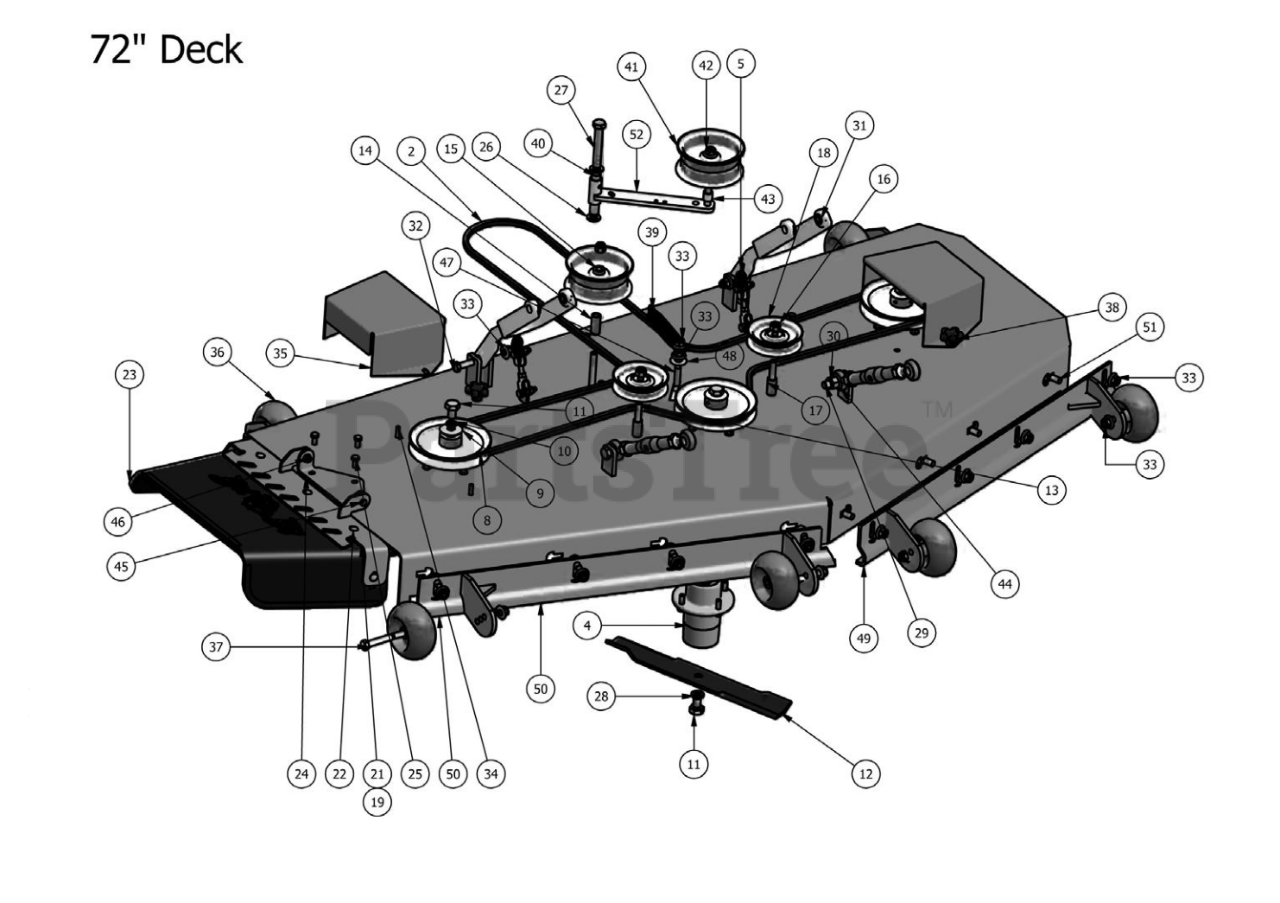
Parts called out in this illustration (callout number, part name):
1	72" Deck Shell
2	72" Deck Belt (Diesel)
3	4 Link Chain Assembly
4	Double Bearing Spindle
5	3/8" x 1 1/4" Hex Bolt
6	3/8" Lock Washer
7	3/8-16 Hex Nuts Zinc
8	7" Deck Pulley
9	Cup Washer
10	1/2" Lock Washer
11	5/8" x 1 1/2" Hex Bolt Grade 8
12	72" Fusion High Lift Blade
13	1/2" x 3 1/2" Grade 8 Bolt
14	1 3/4" Pulley Spacer
15	5 3/4" Deck Idler Pulley
16	1/2" Nylock Nut
17	1 1/2" Diesel Pulley Spacer
18	4 3/4" Idler Pulley
19	72" Lower Hanger
20	5/16" Nylock Flange Nut
21	72" Discharge Chute Upper Hanger Plate
22	5/16" x 1 1/4" Carriage Bolt
23	Rubber Discharge Chute
24	Discharge Chute Hanger (deck mounted)
25	3/8" x 3/4" Hex Bolt
26	.635 ID Plastic Washer
27	5/8" x 4" Hex Bolt
28	5/8" Lock Washer
29	5/8" x 2 1/2" Hex Bolt
30	5/8 Std NC Nylock Nut
31	Deck Arm Assembly
32	1/2" x 2 1/2" Hex Bolt
33	1/2 Nylon Flange Nut-Orange
34	5/16" x 1 1/4" Hex Bolt
35	72" Pulley Cover
36	Anti-Scalp Rollers
37	1/2" x 4" Bolt (Grade 8)
39	Deck Idler Spring 2009
40	5/8 x 1 1/8 Brass Bushing
41	5 3/4" Deck Idler Pulley
42	1/2-13 Nylon Flange Nut-Orange
43	3/4 OD x 1/2 ID x 3\4 Length
44	Turnbuckle (Top Link)
45	5/16" x 1" Hex Bolt
46	5/16" Nylock Flange Nut
47	1/2 x 2" Carriage Bolt
48	1/2" Flat Washer
49	72" Deck Adjustable Front (Left)
50	72" Deck Adustable Front (Right)
51	1/2" x 1 1/4 Carriage Bolt
52	Deck Idler
